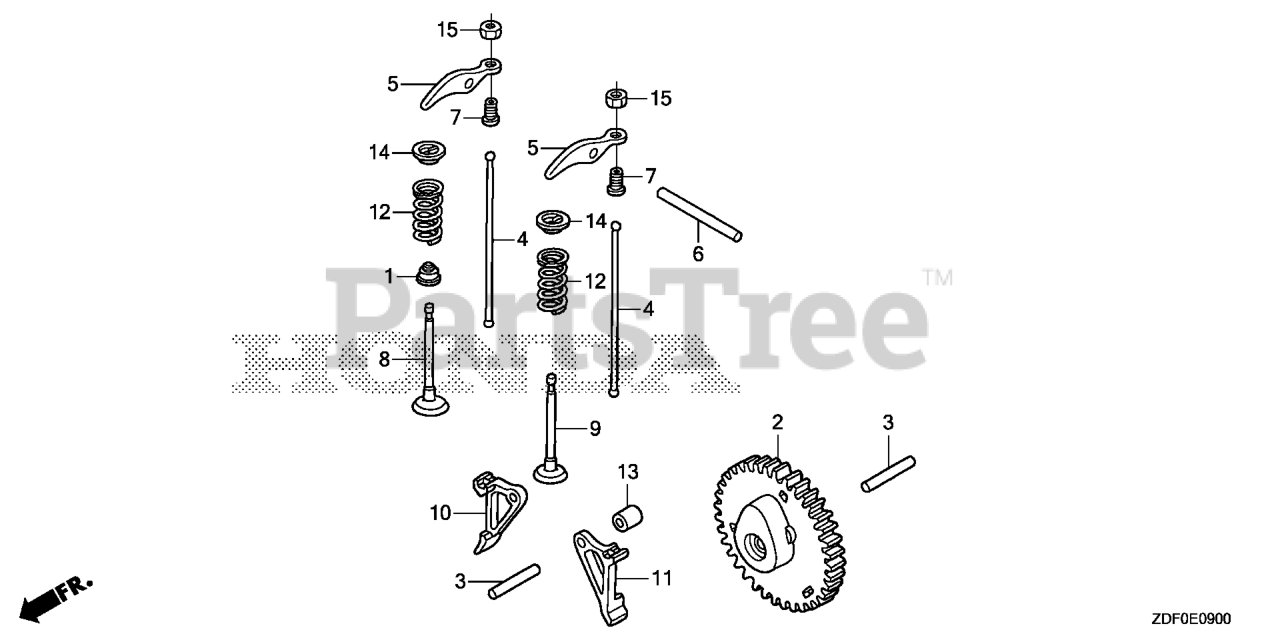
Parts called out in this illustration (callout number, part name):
1	SEAL, VALVE STEM
2	CAMSHAFT ASSY.
3	ROLLER (5X29.8)
5	ARM, VALVE ROCKER
6	ROLLER (4X37.8)
7	PIVOT, ROCKER ARM
8	VALVE, IN.
9	VALVE, EX.
10	LIFTER, VALVE
11	LIFTER, VALVE
12	SPRING, VALVE
13	COLLAR, LIFTER
14	RETAINER, VALVE SPRING
15	NUT, TAPPET ADJUSTING
